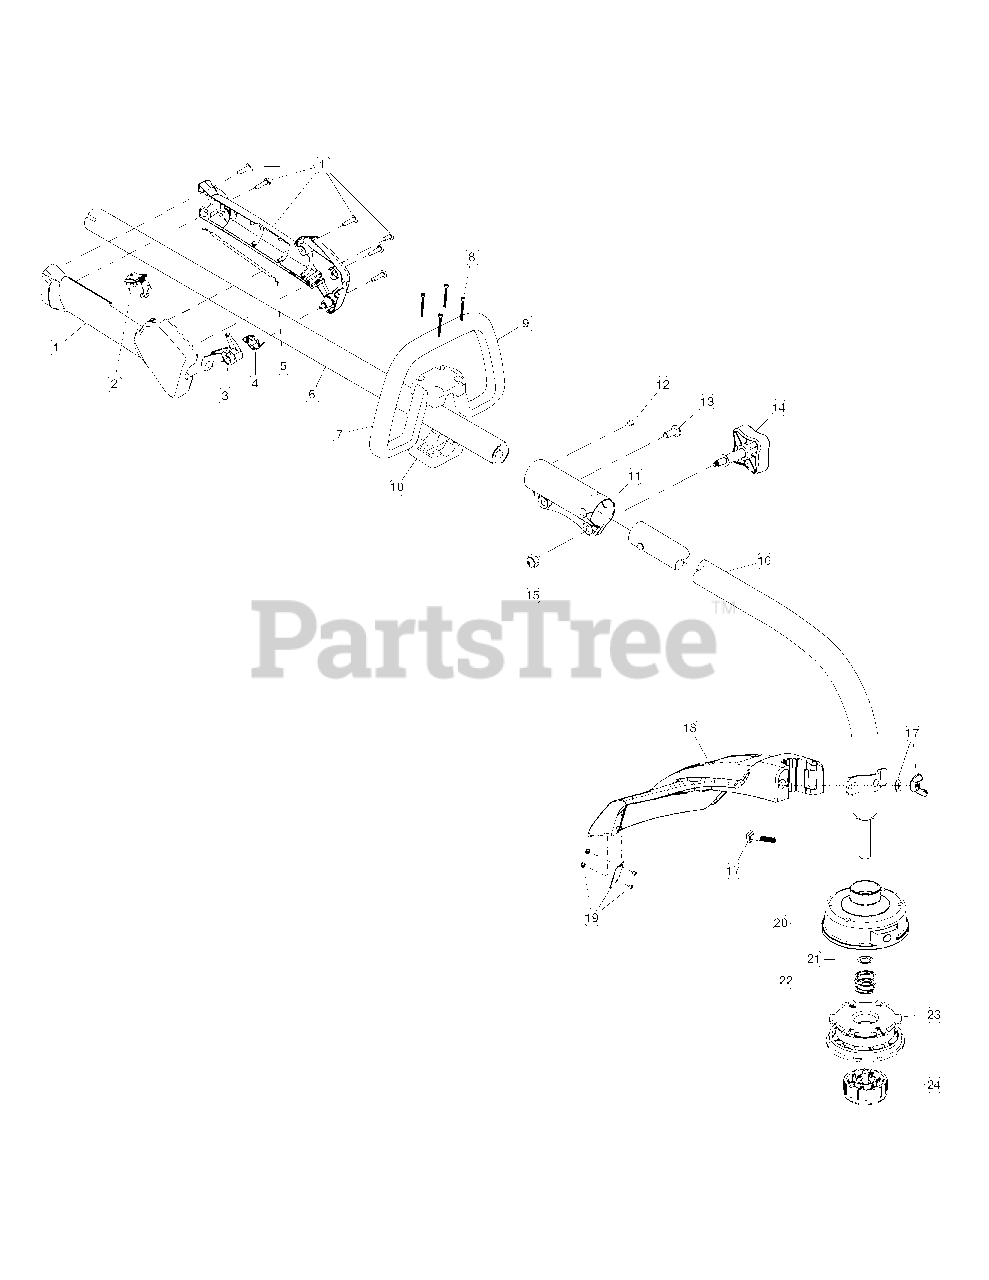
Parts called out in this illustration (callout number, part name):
1	Throttle Housing Assembly (Incl. Ref No. 2-4)
3	Throttle Trigger
4	Throttle Trigger Spring
5	Throttle Cable
6	Upper Drive Shaft Housing Assembly
7	Deluxe D-Handle Assembly (Incl. Ref No. 8-10)
9	D-Handle
10	Bottom Clamp
11	Split Boom Coupler (Incl. Ref No. 12-15)
14	Adjustment Knob
15	Knob Retaining Nut
16	Lower Drive Shaft Housing Assembly
17	Guard Mounting Hardware
18	Guard (Incl. Ref No. 19)
19	Blade Assembly
20	Outer Spool Assembly (Incl. Ref No. 21)
21	Retainer
23	Inner Reel
24	Bump Head Knob Assembly
